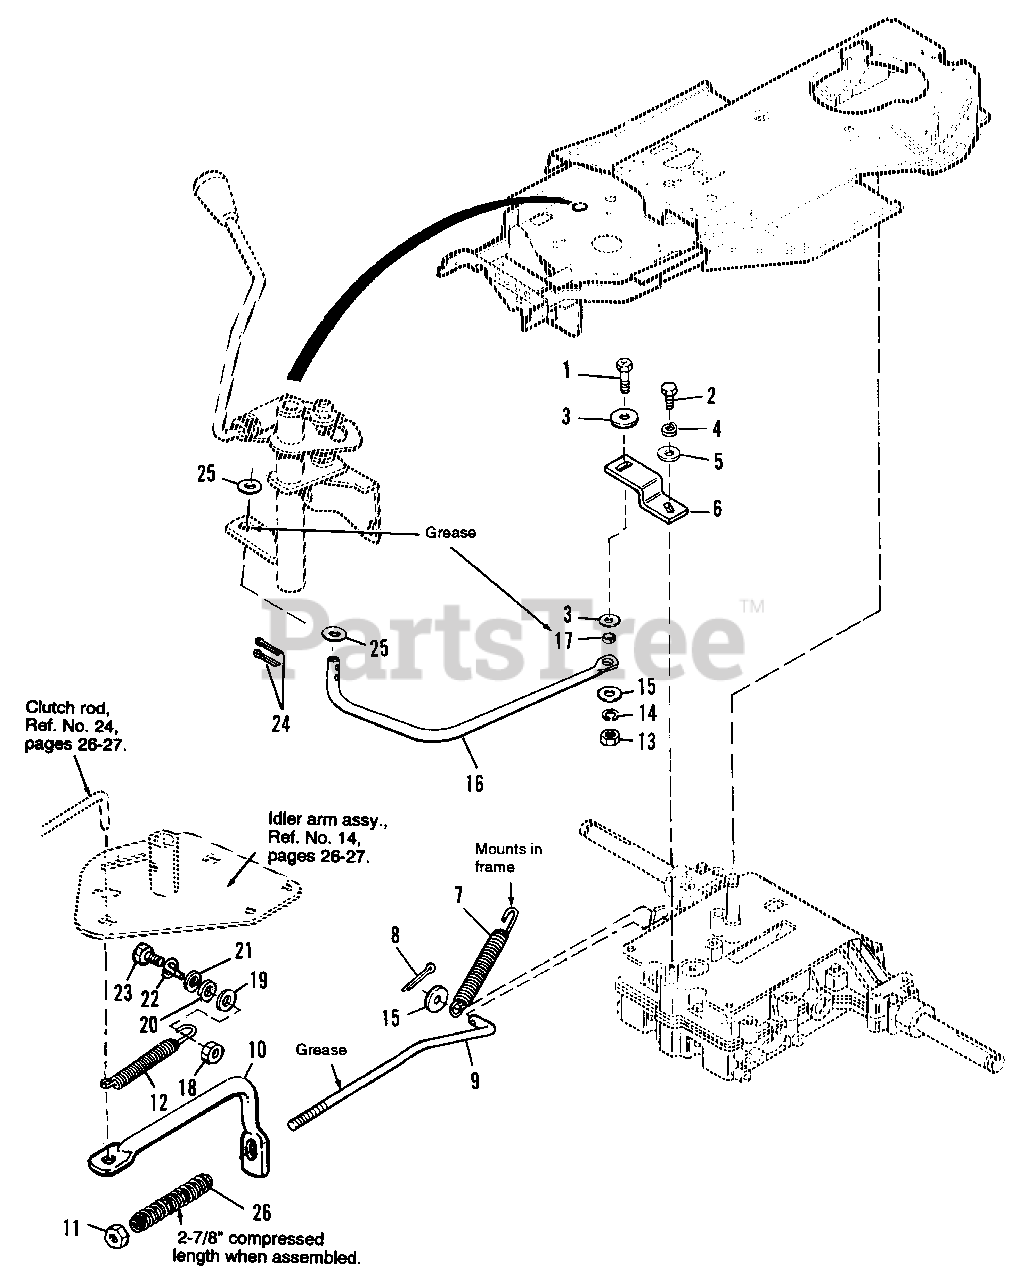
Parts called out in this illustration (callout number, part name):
1	CAPSCREW, Hex, 5/16-18 x 1-1/4
2	CAPSCREW, Hex, 1/4-28 x 5/8
3	WASHER
4	LOCKWASHER, 1/4
5	WASHER, Plain, 1/4
6	LEVER, Shift
7	SPRING, External
8	COTTER PIN, 3/32 x 3/4
10	GUIDE, Brake Rod
11	NUT, Nylon Lock, 5/16-18
12	SPRING, External
13	NUT, Hex, Full, 5/16-18
14	LOCKWASHER, 5/16
15	WASHER, Plain, 5/16
16	ROD, Shift
18	JAM NUT, Centerlock, 3/8-16
19	NUT, Hex, 3/8-16
20	LOCKWASHER, Spring, 3/8
21	WASHER, 3/8
23	CAPSCREW, Hex Hd., 3/8-16 x 1-1/2
24	COTTER PIN, 15/16 x 3/4
25	WASHER, 1/2
26	SPRING, Compression
